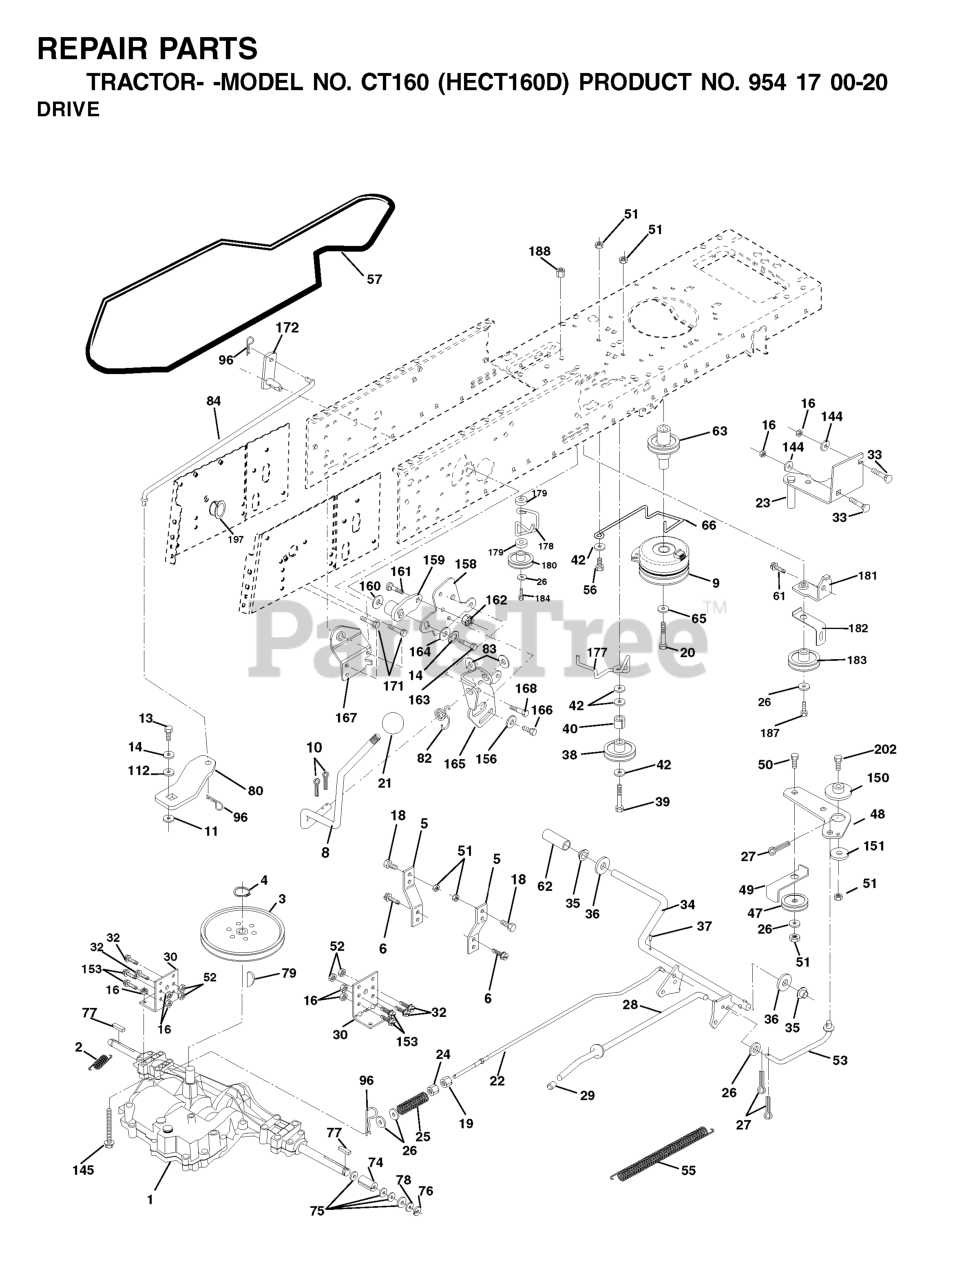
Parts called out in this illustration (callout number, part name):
2	SPRING,BRAKE RETURN
3	PULLEY
4	RETAINING RING LT
5	STRAP TORQUE
6	SCREW 5/16"
8	ROD.SHIFT.FENDER.ADJ.LT.CRD
10	PIN COTTER
11	WASH-SHFT PLT LT
13	BOLT 1/4-28X3/4
14	LOCKWASHER
16	NUT.71038.31-18.HEX.NYLOCK
19	NUT
20	BOLT HEX
21	KNOB.DUCKHEAD.1/2
23	BRACKET.ASM.CLUTCH
24	NUT
25	SPRING ROD LT
26	WASHER
27	COTTER PIN
28	ROD BRAKE PARK LT
29	PLUNGER CAP
30	BRKT, MOUNT TRNSAXLE
32	BOLT
33	RP BOLT 5/16-18 X3/4 ZN/YEL GR
35	BEARING.NYLON
37	DRIVE PIN
38	PULLEY.FLAT
42	WASHER
47	IDLER PULLEY
48	BELLCRANK, CLUTCH
49	RETAIN BELT
50	BOLT
52	LOCKNUT
53	LINK, CLUTCH LT
55	SPRING, RETURN LT
57	V-BELT.KEV.111"
61	SCREW 3/8-16X3/4
62	COVER, PEDAL (1 2)
63	PULLEY, CLUTCH ELECT EVX
65	LOCKWASHER
66	KEEPER BELT ENGINE
74	SPACER AXLE
77	SQUARE KEY
79	KEY STD (1373) DANA
82	SPRING,TORSION
83	WASHER
96	RETAINER M
144	Washer 11/32 x 5/8 x 16 Ga SD
150	BUSHING.BELLCRANK.GRD.DR
151	WASHER 12/32X2X10GA
153	BOLT RB
156	WASHER.SRRTD.5/16
158	BRACKET
159	HUB
160	Washer 29/32 x 1 - 1/4 x 16 Ga.
161	BOLT
162	NUT.CROWNLOCK.1/4
164	Washer 5/8 x .281 x 10 Ga.
165	RP BRACKET
167	BRACKET.SUPT.SHIFT.CRD
168	BOLT.SHOULDER.5/16-18X
172	SHAFT
180	PULLEY.FLAT.IDLER
181	BRKT.IDLER.GRD.DR.CRD
182	KEEPER BELT
183	PULLEY.V-IDLER
184	SCREW.HXWSH.3/8
187	SCREW
188	SNAP BUSHING T
197	NYLINER SNAP 5/8" ID
202	BOLT.3/8-16X1.50
